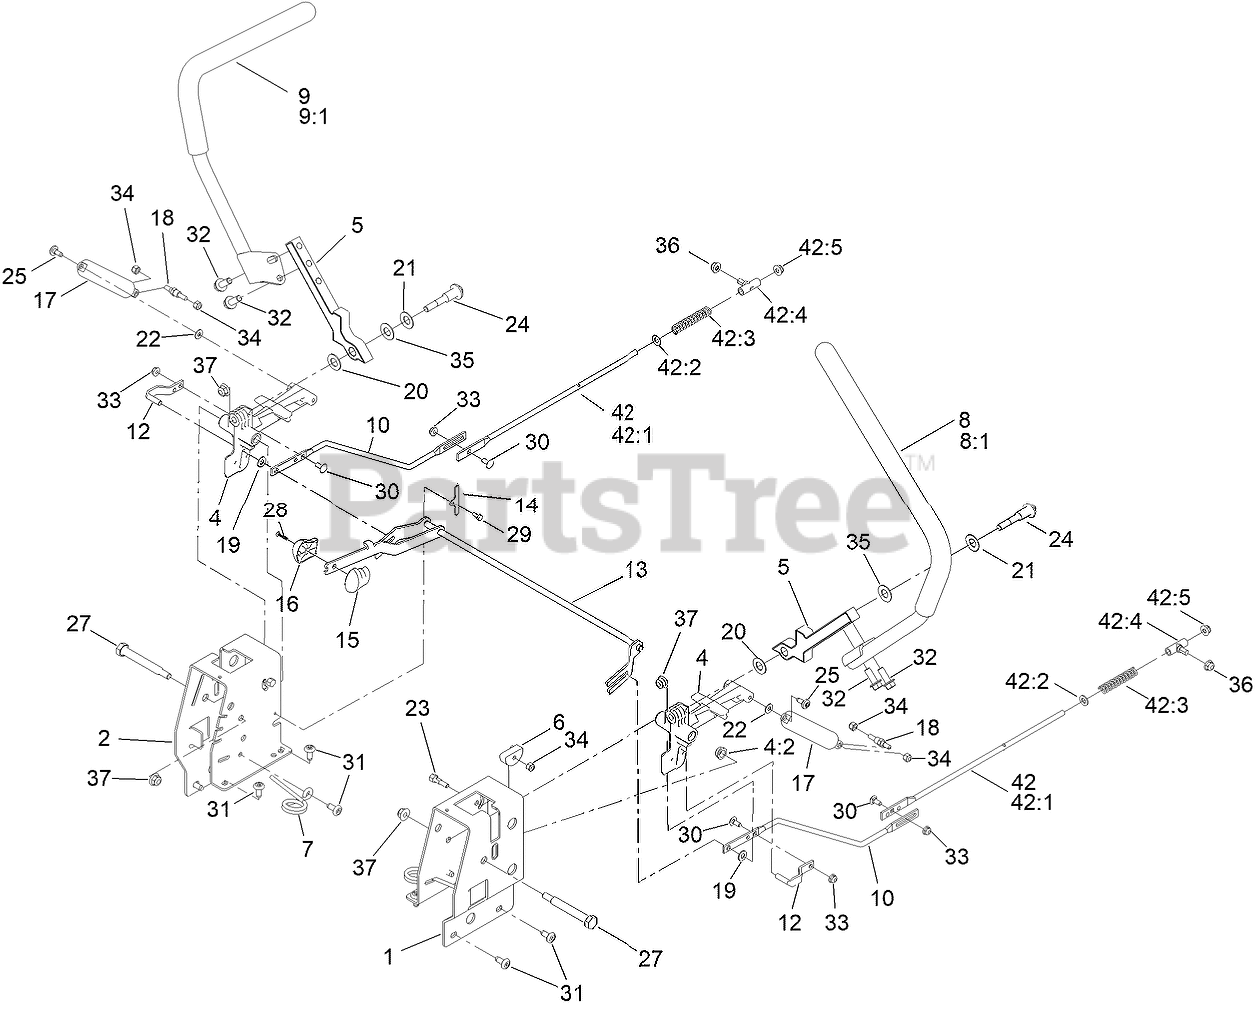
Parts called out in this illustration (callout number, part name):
1	PLATE-CONTROL BOX, LH
2	PLATE-CONTROL BOX, RH
4	ACTUATOR ARM ASM
4:2	BUSHING-FLANGE
5	ARM-CONTROL
6	ECCENTRIC
7	SPRING-TORSION
8	HANDLE-CONTROL, LH
9	HANDLE-CONTROL, RH
10	ROD-HYDRO, FRONT
12	PIN-ROD, HYDRO
13	SPEED CONTROL ASM
14	PLATE-RETAINER
15	KNOB-RH
16	KNOB-LH
17	DAMPER-NON CAVITATING
18	STUD-DAMPER
19	SPACER-NYLON
20	WASHER-NYLON
21	WASHER-BELLEVILLE
22	WASHER
23	BOLT-PIVOT, ECCENTRIC
24	BOLT-PIVOT
25	SCREW-SHOULDER
27	BOLT-PIVOT
28	SCREW-PPH
29	SCREW-TAPTITE
30	BOLT-CARR
32	SCREW-HHF
33	NUT-HF
34	NUT-HEX
35	WASHER
36	NUT-HF
37	NUT-HF, NI
42	ROD HYDRO ASM
42:1	ROD-HYDRO, REAR
42:2	WASHER-PLAIN
42:3	SPRING-COMPRESSION
42:4	MOUNT-ROD, HYDRO
42:5	NUT-HF
